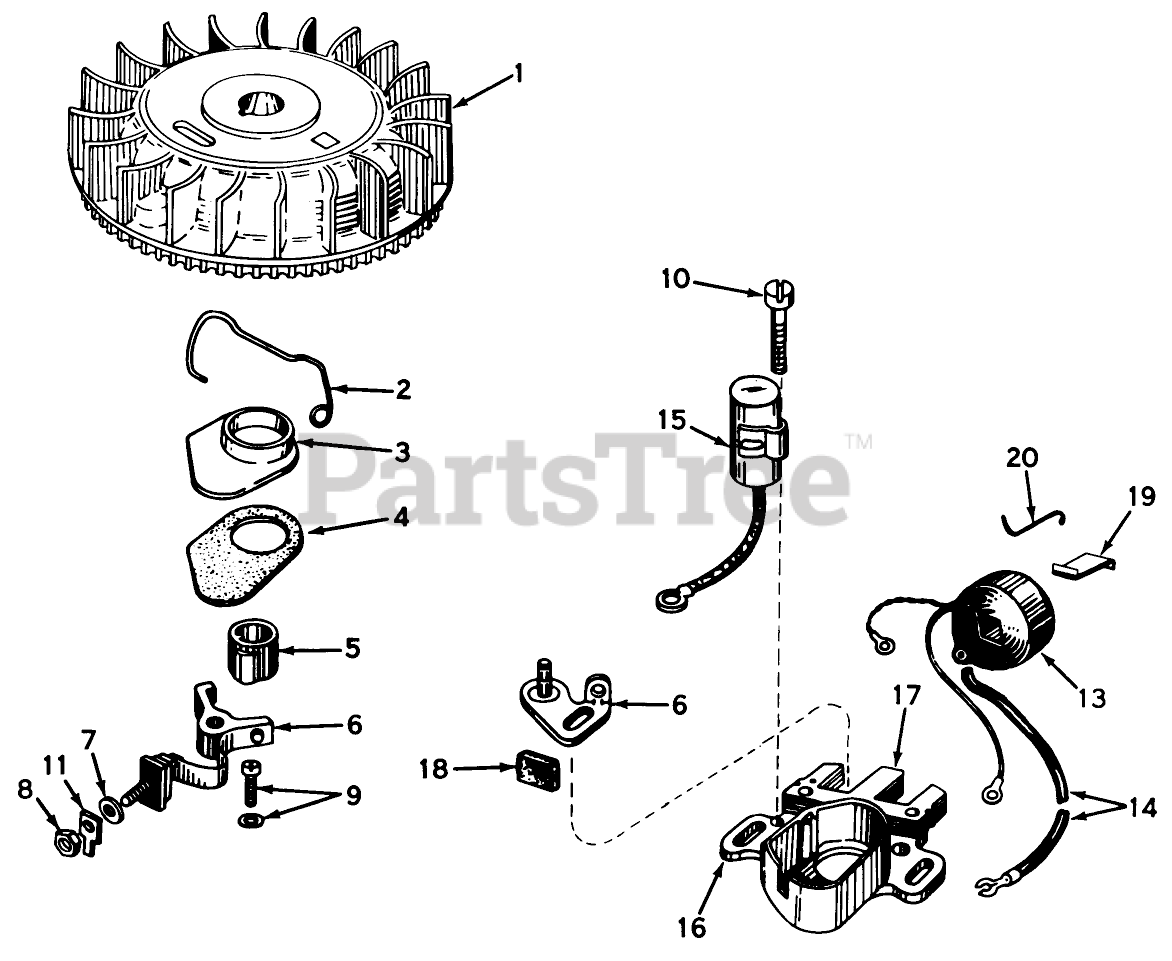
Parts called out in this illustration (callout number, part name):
1	FIywheel
2	Spring Breaker Box
3	Cover, Dust
4	Gasket Dust Cover
5	Cam, Breaker
6	Breaker Assy.
9	Breaker Screw
10	Condenser Screw
11	Terminal
13	Coil Assy. (Incl. Ref. 14, 15 & 19)
14	Wire, Lead
15	Condenser
16	Core & Plate
17	Stator Assy. (Incl. Ref. 2, 3, 5 thru 14 & 16 thru 19)
18	Felt,Cam Wiper
19	Spring Coil Wedge
20	Clip, Coil
